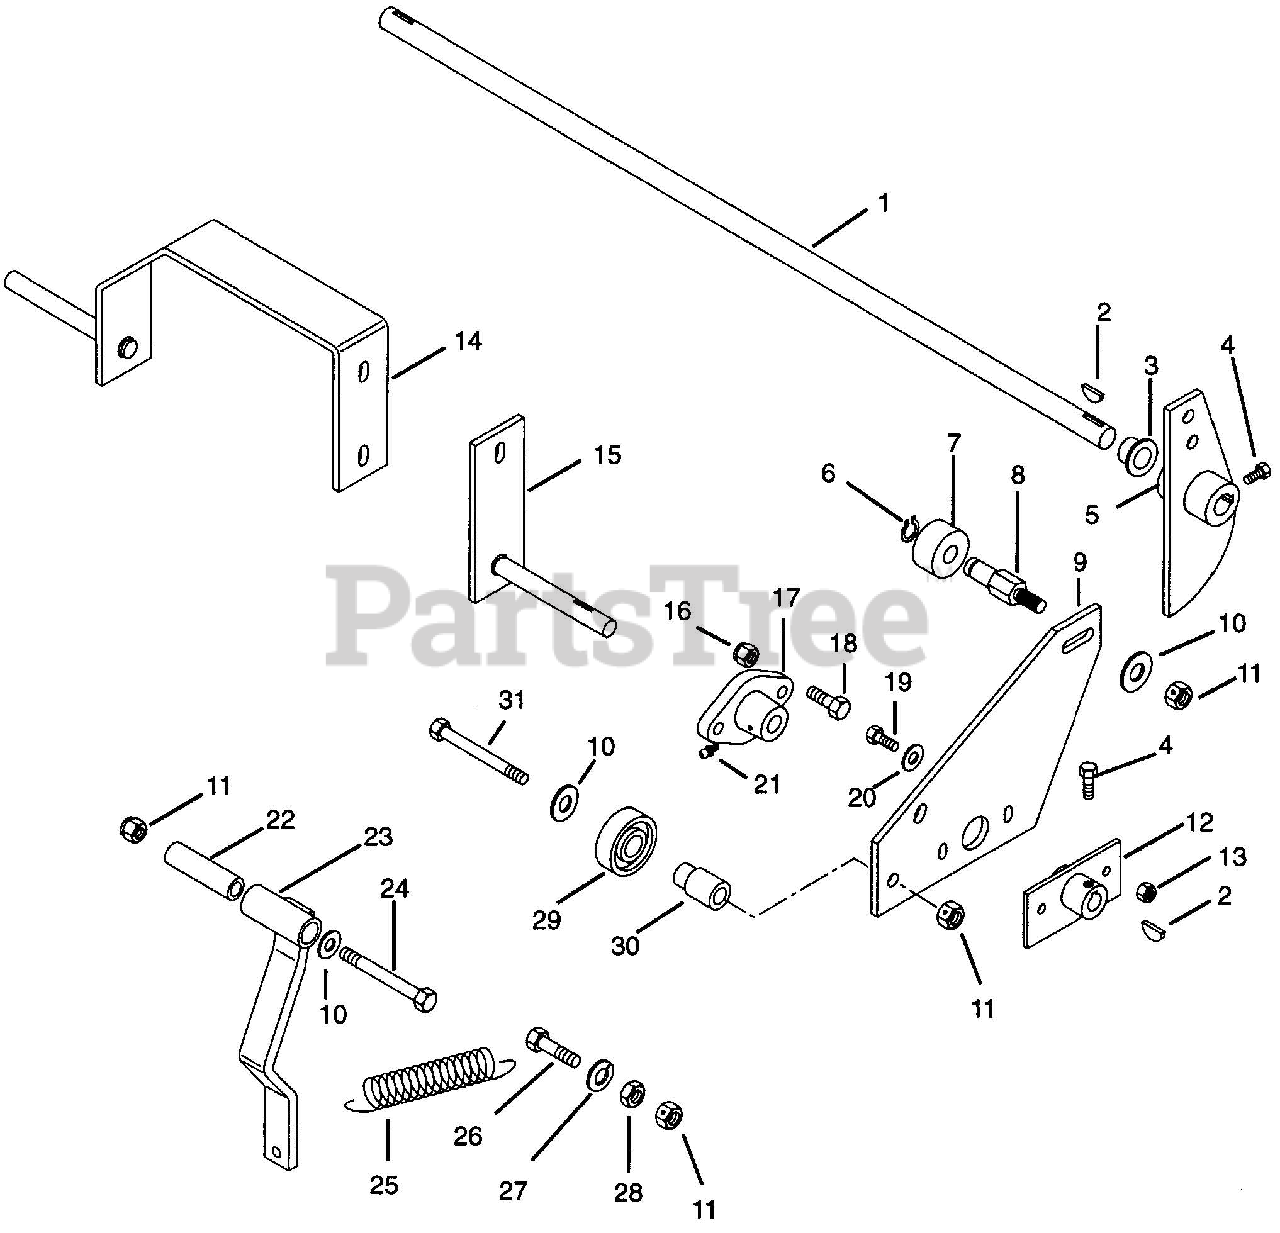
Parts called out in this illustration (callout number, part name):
1	Shaft - Speed Control Cam
2	Key - Woodruff .13 x .75
3	Bushing-Flang .630 x 1.000 x .625
4	Bolt-Hex .25-20 x .50 Grade 5
5	Weldment - Control Cam
6	Ring-Retaining-Internal 2.68 x .049
7	Roller - Nylon
8	Pin - Roller
9	Arm - Speed Control
10	Washer-Flat-Steel .406 x .812 x .065
11	Nut-Locking-Center .38-16
12	Weldment - Neutral Adjustment
13	Nut-Locking-Center .250-20
14	Weldment - Pump Control - Right Hand
15	Weldment - Pump Control - Left Hand
16	Nut-Locking-Center .31-18
17	Bushing-Flanged Support
18	Bolt-Hex .31-18 x 1.00 Grade 5
19	Bolt-Hex .25-20 x .75 Grade 5
20	Washer-Flat-Steel .81 x .625 x .065
21	Fitting - Lube .25-28 x .256
22	Bushing-Steel .385 x .610 x 1.80
23	Weldment - Detent Strap
24	Bolt-Hex .38-16 x 2.75 Grade 5
25	Spring-Tens .063 x .62 x 2.75
26	Bolt-Hex .38-16 x 1.50 Grade 5
27	Washer-Lock .375 x .094
28	Nut-Hex .375-16
29	Bearing-Ball .500 x 1.375 x .437
30	Hub - Bearing Mount
31	Bolt-Hex .38-16 x 2.00 Grade 5
